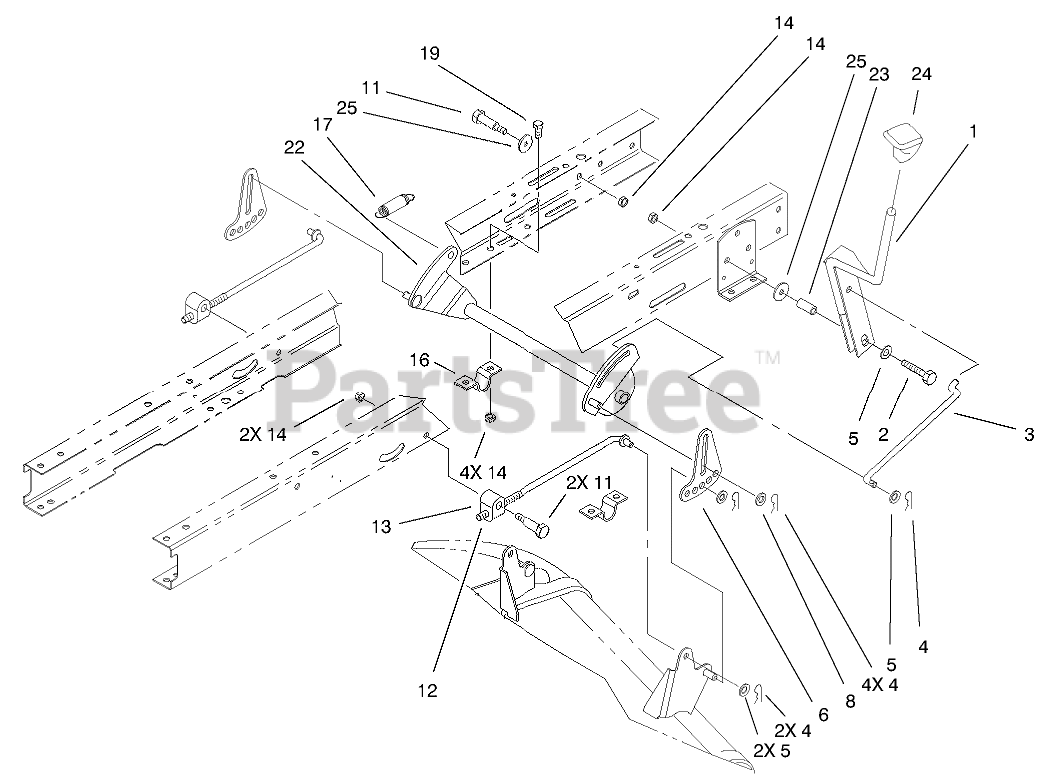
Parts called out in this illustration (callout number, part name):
1	HOC LEVER ASM
2	SCREW-HH
3	LINK-HOC
4	PIN-COTTER
5	WASHER-FLAT
6	LINK-ADJUSTING, HOC
8	WASHER-HARDENED
11	SCREW-SHOULDER, HH
12	ROD-HANGER, REAR
13	TRUNNION-HOC
14	NUT-LOCK, NI
16	CLAMP-PIVOT, HOC
17	SPRING-EXTENSION
19	SCREW-HH
22	PIVOT ASM
23	SPACER
24	KNOB-SHIFT
25	WASHER-PIVOT
